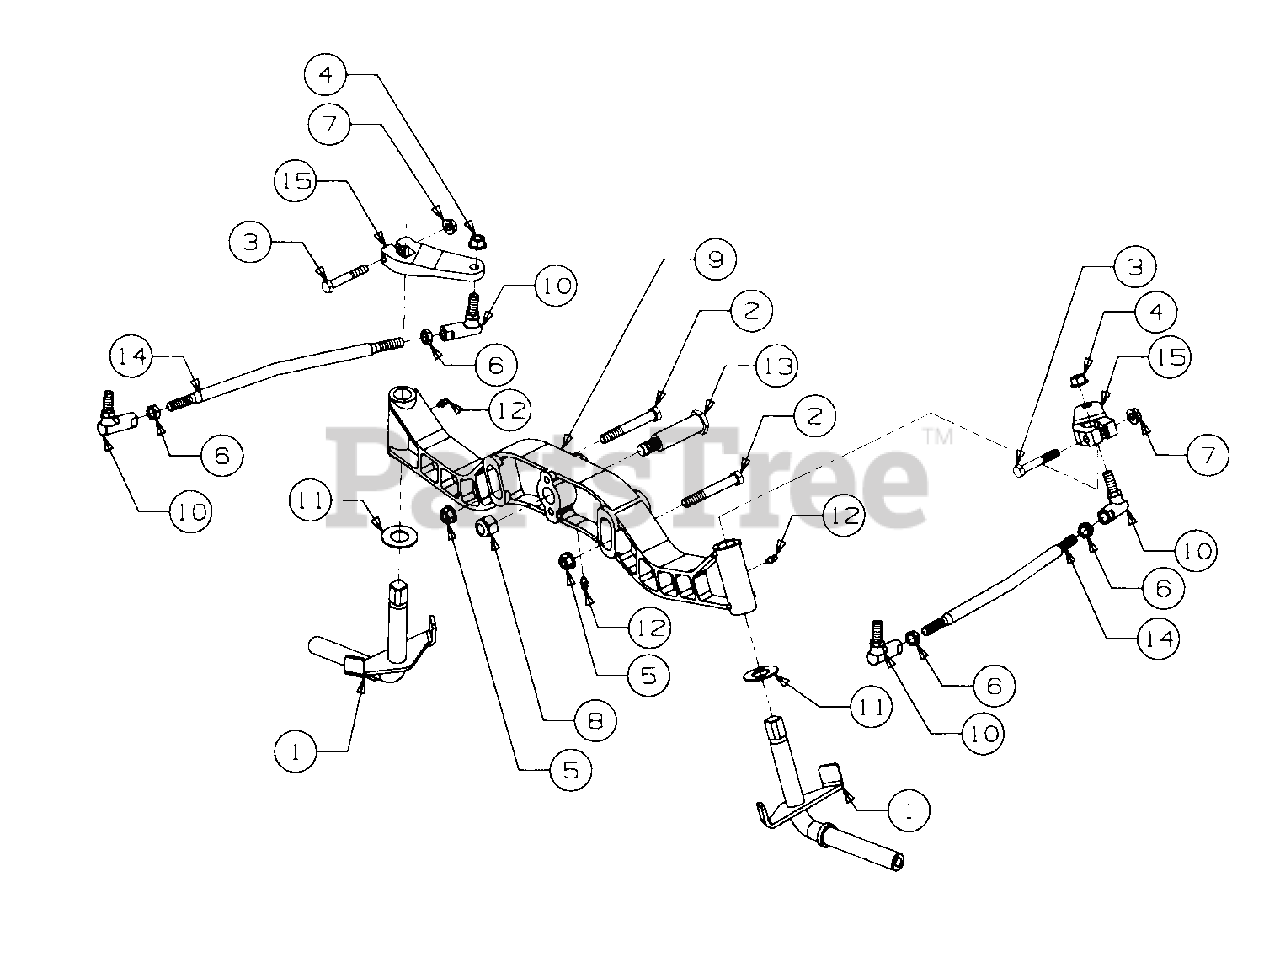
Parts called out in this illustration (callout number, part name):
1	Knuckle Assy, Steering
2	Screw, Hex Cap, 3/8-16 x 2.75 Lg GR8
3	Screw, Hex Cap, 5/16-18 x 2.0 Lg GR2
4	Nut, Hex Lock, 3/8-24 GR5
5	Nut, Hex Flanged Lock, 3/8-16
6	Nut, Hex Jam, 3/8-24 GR5
7	Nut, Hex Flange Top Lock, 5/16-18
8	Nut, Hex Top Nylon Lock, 1/2-13
9	Axle, Front Pivot
10	Joint, Ball, 3/8-24
11	Washer, Flat, .760 x 1.49 x .06 Thk Hdn
12	Fitting, Lube, 3/16 Drive Type
13	Bolt, Pivot Shoulder, 3/4 Dia x 2.23 Lg
15	Arm, Steering
